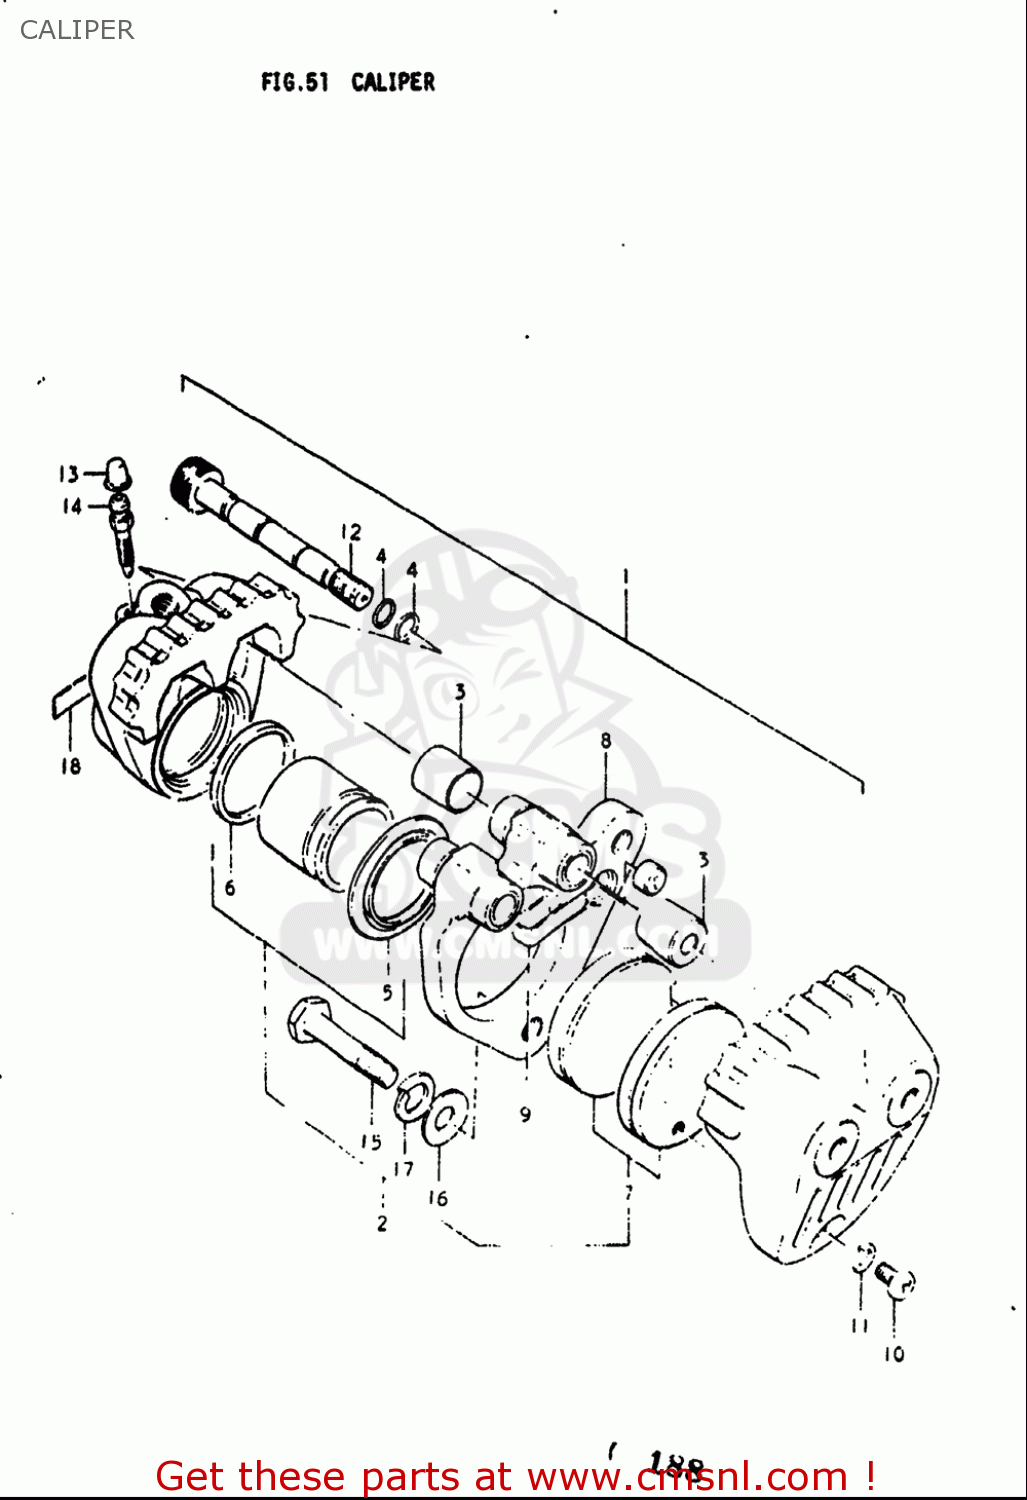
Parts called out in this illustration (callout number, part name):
2	PISTON SET
3	COVER,AXLE DUST
4	O RING,CALIPER AXLE
5	BOOT,PISTON
6	SEAL,PISTON
7	PAD SET (NAS)
10	SCREW
11	WASHER,LOCK
13	CAP,BLEEDER PLUG
14	BLEEDER
15	BOLT(10X38)
16	WASHER
17	WASHER,LOCK
